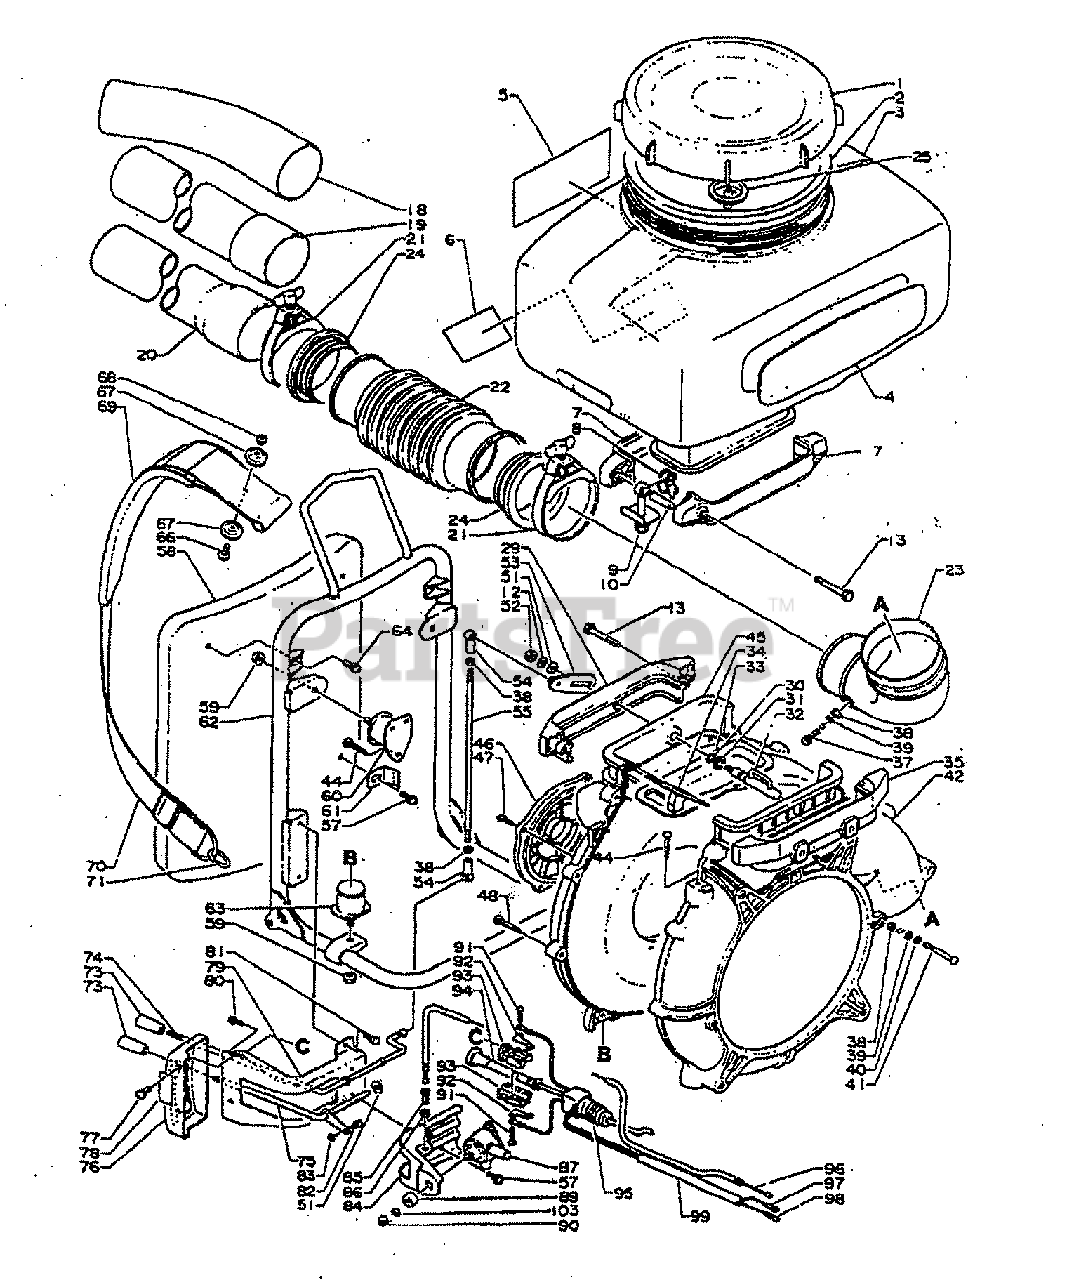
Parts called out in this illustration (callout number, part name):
1	Cap, Tank
2	Gasket, Tank
3	Tank, Chemical 16R
4	Label
13	Screw
18	Pipe, Curved
19	Pipe, Straight
20	Pipe, Straight
22	Pipe, Flexible
23	Elbow, Blowing
24	Packing, Fix. Pipe
25	Cap, Inner
32	Shaft, Shutter
37	Screw 5 x 14
38	Nut 5
40	Washer, Spring 5
42	Case, Fan
44	Screw 5 x 16
45	Case, Fan
46	Grid. Fan Case
47	Screw 5 x 16
48	Screw
53	Arm, Shutter
54	Connector
55	Rod, Dust Control
57	Screw 5 x 10
58	Plate, Black Cushion
59	Nut, Flange
61	Bracket
62	Frame, Knapsack
64	Screw 5 x 12
66	Screw 5 x 14
68	Lock nut
69	Pad, Shoulder
70	Harness, Knapsack
73	Knob
75	Control, throttle
77	Screw 5 x 14
79	Bracket, dial
80	Screw 4 x 10
81	Bolt 5 x 10
84	Holder, lever
87	Valve ass'y fuel
89	Spacer
91	Screw 3 x 16
93	Knob, Switch
94	Rod, Stop Switch
95	Cover, Stop Switch
96	Wire, Throttle
97	Lead, Ground
103	Washer, Spring
